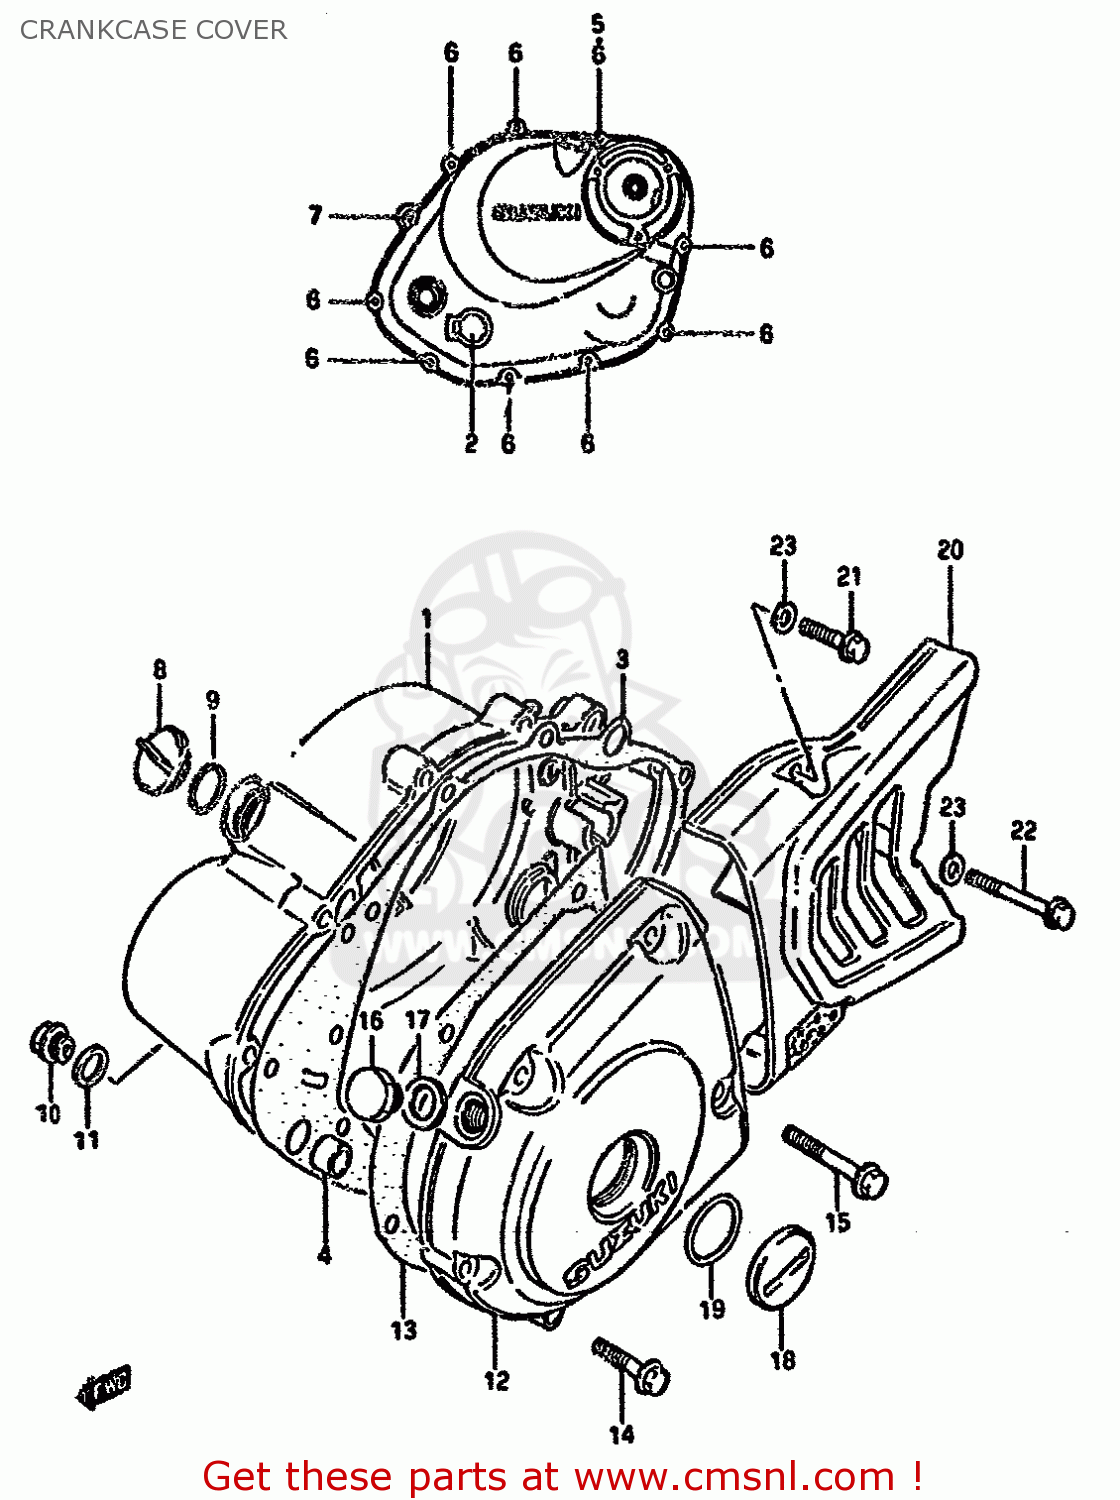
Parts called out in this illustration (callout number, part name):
1	COVER,CLUTCH
2	LENS,OIL LEVEL CHECK
3	GASKET,CLUTCH COVER (MCA)
4	PIN
5	GASKET(5.8X13X1.2) (NAS)
6	BOLT 6X30
7	BOLT
8	PLUG
9	O RING(D:3.1,ID:16.8)
10	PLUG(14X12)
11	GASKET(14X19.2X2) (NAS)
12	COVER,MAGNETO
13	GASKET,MAGNETO COVER (MCA)
14	BOLT 6X30
15	BOLT 6X40
16	PLUG(12X9)
17	GASKET(12.1X16.2X3.7) (NAS)
18	PLUG
19	O RING(D:3.1,ID:22.7)
20	COVER,ENGINE SPROCKET
21	BOLT
22	BOLT
23	WASHER,5MM
